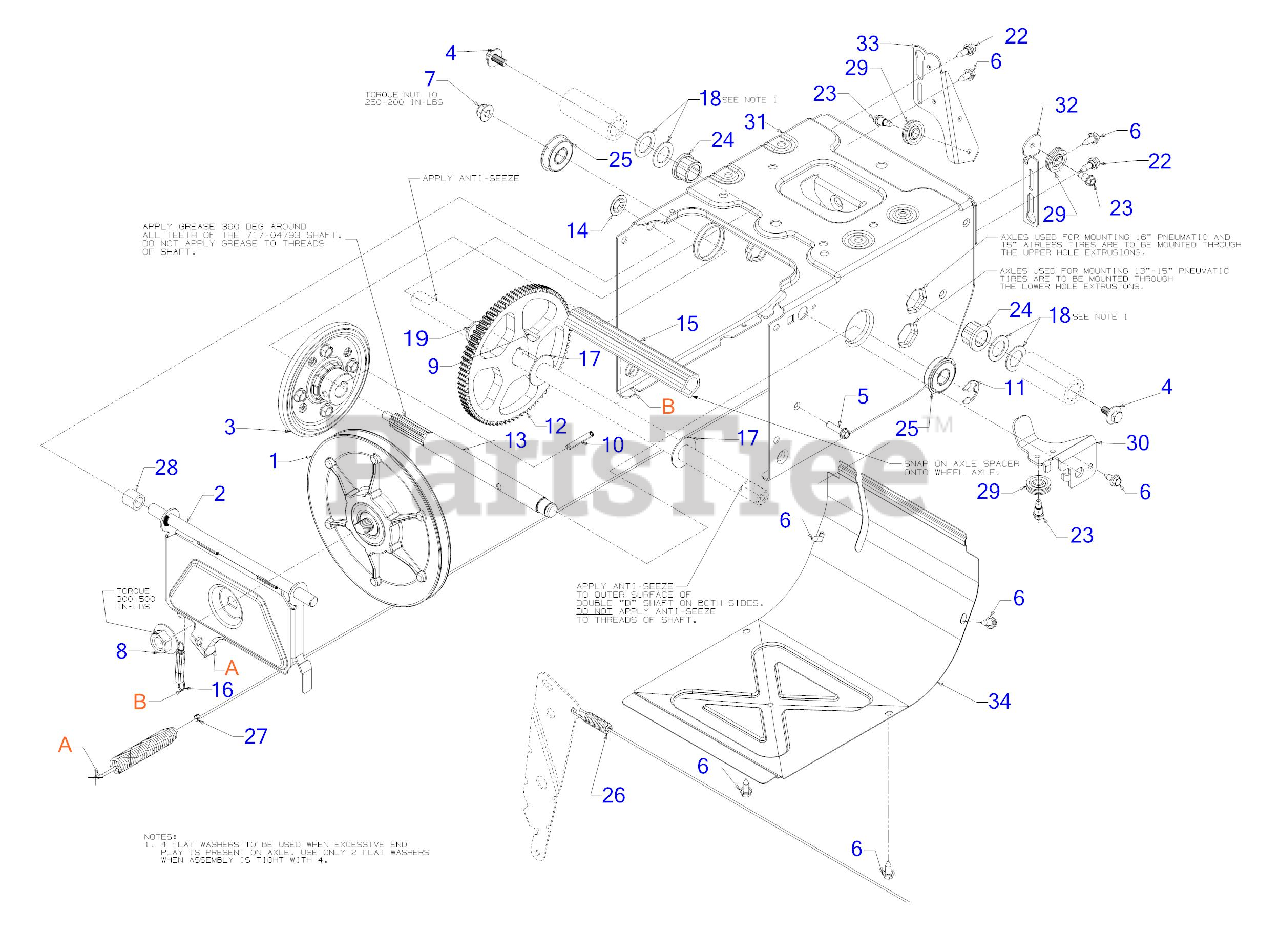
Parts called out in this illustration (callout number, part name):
1	FRICTION WHEEL DISC ASSEMBLY
2	FRICTION WHEEL BRACKET
3	FRICTION WHEEL ASSEMBLY
4	SCREW 5/16-24 x .750 GR5
5	SCREW 1/4-20 x 1.00
6	SCREW 1/4-20X.625
8	FLANGE NUT 5/8-18
9	KEY 3/16 x 3/4
10	SPIRAL PIN
11	E-RING
12	GEAR:80 TOOTH
13	SHAFT-.75 DIA
14	PUSH CAP
15	SPACER-AXLE 7.40"
16	EXTENSION SPRING
17	FLAT WASHER .760ID X1.49OD x .06
18	FLAT WASHER .793ID x 1.24OD x .060
19	FLAT WASHER .750X1.000X.060:HD
22	SHOULDER SCREW
23	SHOULDER SCREW
24	FLANGE BEARING
25	BALL BEARING
26	AUGER DRIVE CABLE 47.48"
27	WHEEL DRIVE CABLE 44.955"
28	SPACER-.513 ID x .703 OD x .69
29	CABLE GUIDE ROLLER
30	AUGER CABLE BRACKET
32	AUGER CABLE GUIDE BRACKET
33	GUIDE BRACKET
34	FRAME COVER
